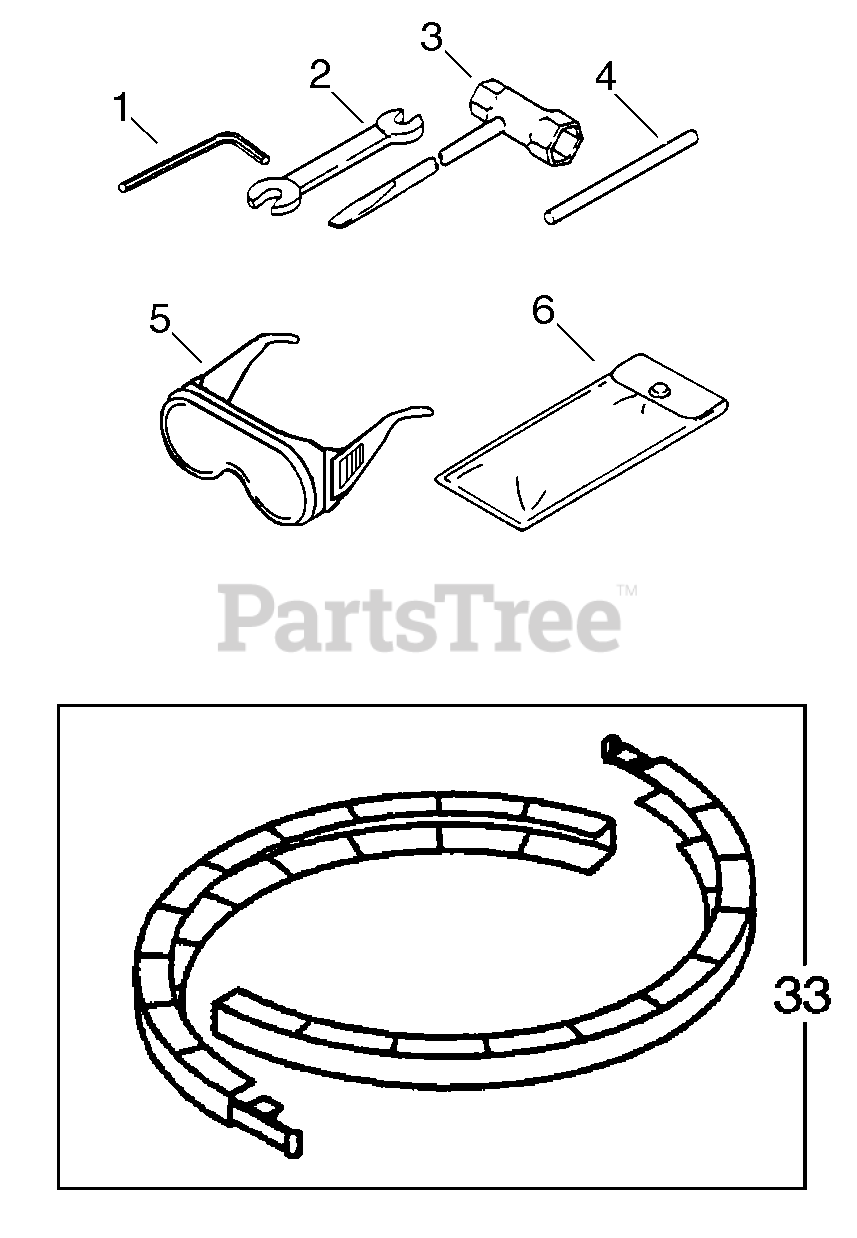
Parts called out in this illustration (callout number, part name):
1	WRENCH, ALLEN 4 MM
2	SPANNER 8×10
3	T-WRENCH 17x-19 L200
4	TOOL, LOCKING 5×120 MM
5	GLASSES, SAFETY
6	BAG, TOOL
33	SCABBARD
